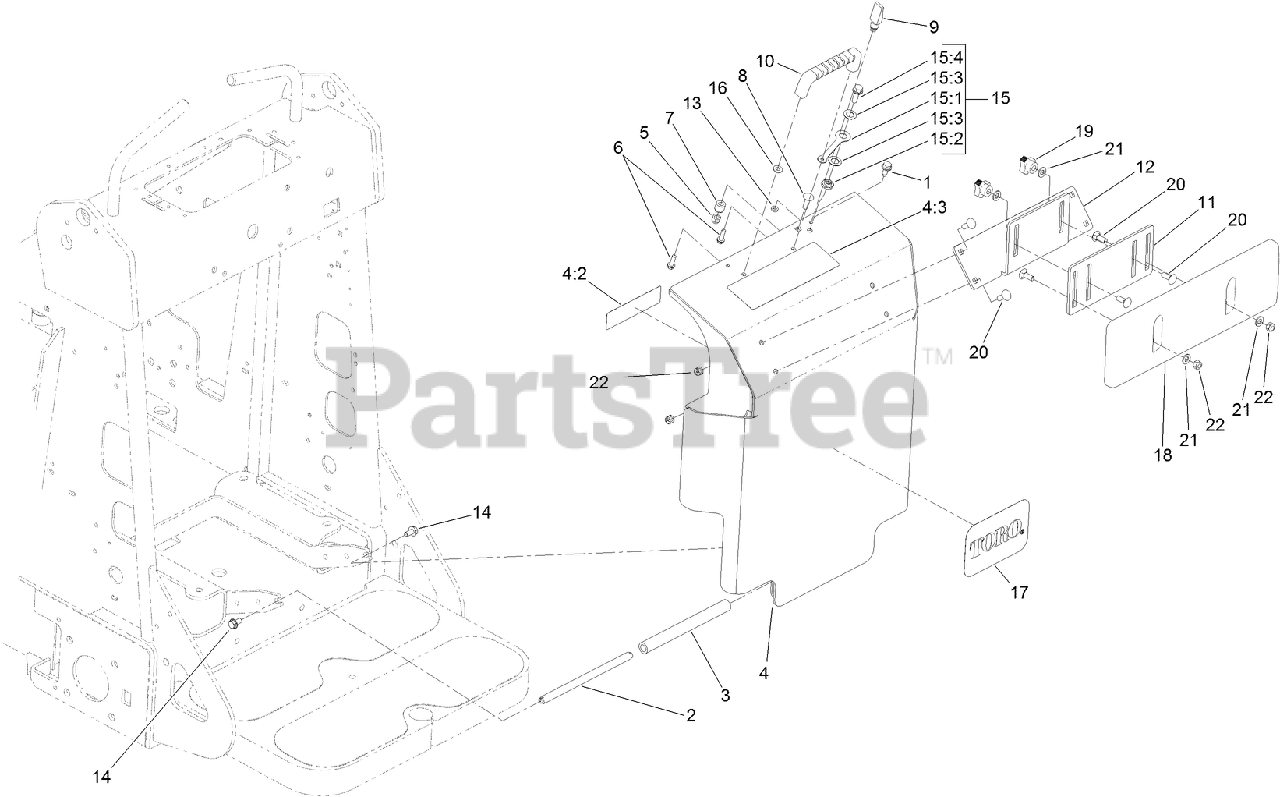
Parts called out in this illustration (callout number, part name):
1	SCREW-HWHTF
2	BAR-HINGE
3	HOSE-HINGE
4	COVER ASM
4:2	DECAL-DANGER
4:3	DECAL-DANGER
5	NUT-ACORN
6	SCREW-HWH
7	SPACER-GUIDE
8	SCREW-CARR
9	LATCH-SWELL
10	HANDLE-DOOR
11	PLATE-ADJUSTING
12	BRACKET-SUPPORT, THIGH
13	WASHER
14	SCREW-HHF
15	LANYARD ASM
15:1	LANYARD-3 INCH
15:2	NUT-SHOULDER
15:3	WASHER
15:4	SCREW-HHF
16	WASHER-FLAT
17	DECAL
18	SUPPORT-THIGH
19	KNOB-ADJUSTMENT
20	SCREW-CARR
21	WASHER-FLAT
22	NUT-LOCK, NI
